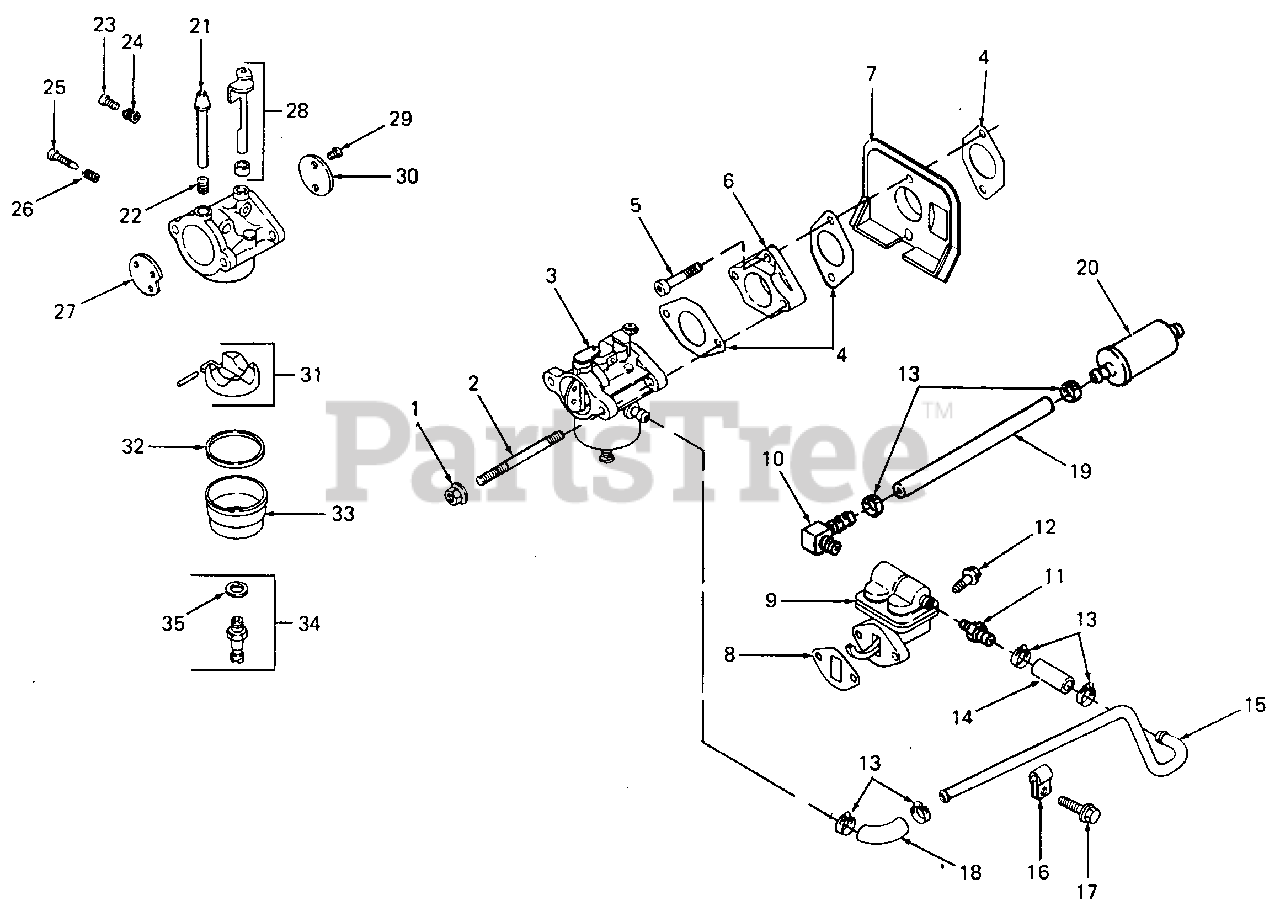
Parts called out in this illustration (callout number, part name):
1	Nut, Carburetor, M6 X 1.0
2	Stud, Carburetor
3	Carburetor Assy w/Gasket
4	Gasket, Carburetor
5	Screw, Manifold Mounting
6	Manifold, Carburetor
7	Deflector, Heat
8	Gasket, Fuel Pump
9	Pump, Fuel
10	Connector, 90
11	Connector, Straight Hose
12	Screw, Fuel Pump Mounting
13	Clamp, Fuel Line
14	Line, Fuel - Metal Line to Pump
15	Line, Fuel - Metal
16	Clamp, Fuel Line
17	Screw, Fuel Line Clamp
18	Line, Fuel - Metal Line to Carb
19	Line, Fuel - Pump to Filter
20	Filter, Fuel
21	Shaft, Choke
22	Spring, Choke Return
23	Screw, Throttle Adj
24	Spring, Needle
25	Screw, Idle Needle
26	Spring, Needle
27	Plate, Choke
28	Shaft, Throttle
29	Screw, Valve
30	Plate, Throttle
31	Kit, Float Assembly
32	Gasket, Fuel Bowl
34	Kit, Adjustable Needle
35	Gasket
